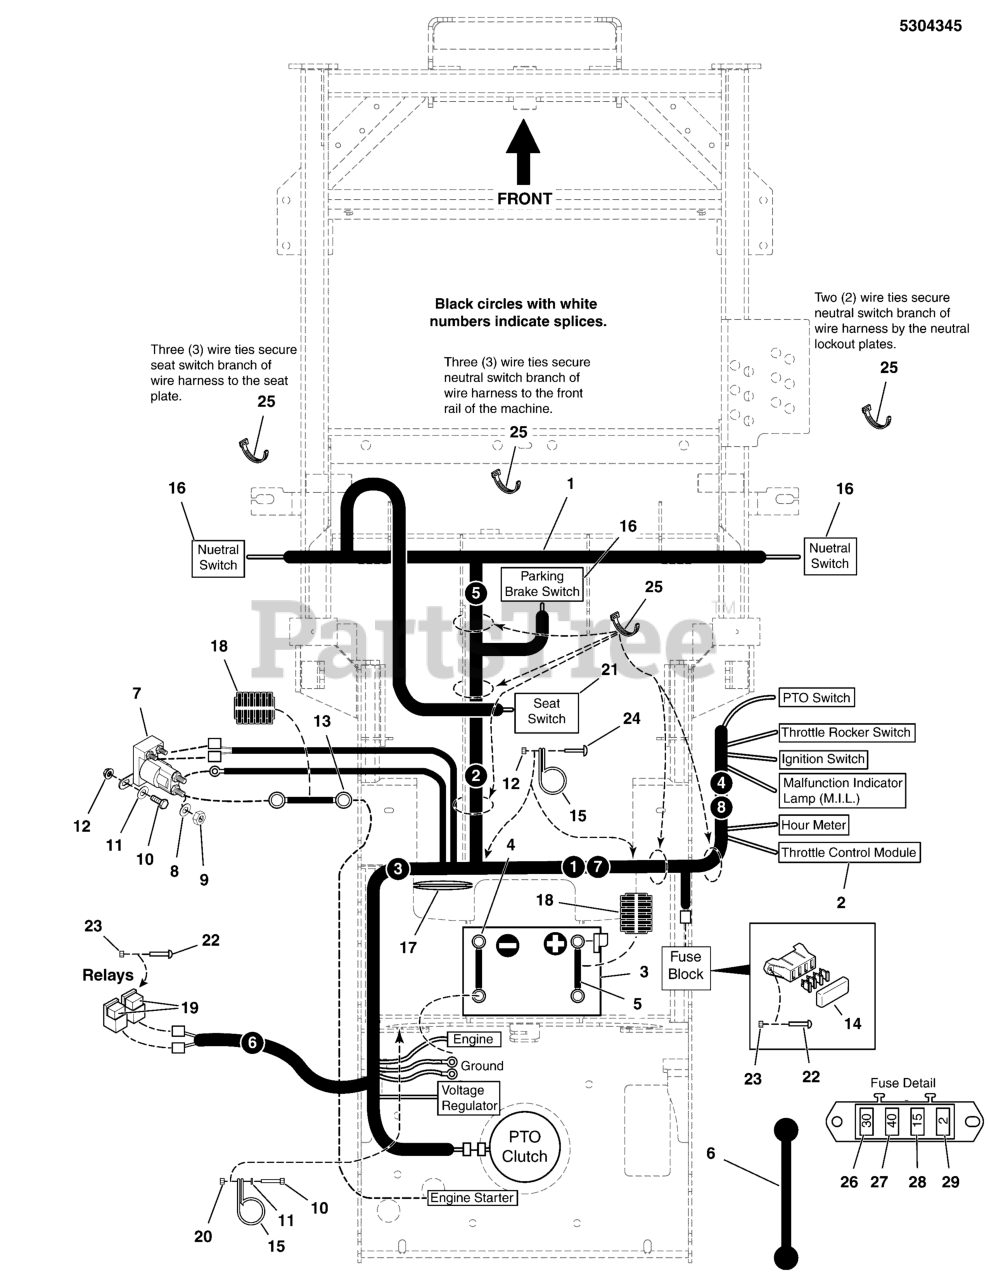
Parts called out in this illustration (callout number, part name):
1	WIRE HARNESS, IS700, KAWI FS730V EFI
2	MODULE, THROTTLE CONTROL, KAV DFI
3	BATTERY, WET ( BCIU1, 350 CCA)
4	BATTERY CABLE, NEG, 14, 5/16-13/32
5	BATTERY CABLE, POS, 22, 1/4-5/16
6	STRAP-BLACK RUBB
7	SOLENOID-4 POLE 12 VOLT DC (TROMBETTA)
8	WASHER, 5/16 LIGHT LOCK
9	NUT, 5/16-24 JAM
10	BOLT, 1/4-20 X 3/4 GD5 CZ
11	WASHER, 1/4 SAE
12	NUT, 1/4-20 HEX SERR. FLANGE
13	BATTERY CABLE, POS, 22, 1/4-5/16
14	COVER, VINYL, FUSE BLOCK
15	CLAMP, VINYL INSULATED, 1.00
16	SWITCH, DP NO/NC SNAP-IN
17	GROMMET, 1-1/2" ID FOR 1/4" METAL
18	WIRE LOOM, 3/8 ID X 18 IN
19	RELAY, 12V, 40A
20	NUT, 1/4-20 HEX NYLOCK FLANGE
21	DELTA SWITCH - NORMALLY CLOSED
22	SCREW, #10-24 X 3/4 ROUND PHILLIPS
23	NUT, #10-24 HEX NYLON LOCK
25	TIE, SELF-LOCKING, 12"
26	FUSE, ATO, 30 AMP
27	FUSE, ATO, 40A
28	FUSE, ATO-15 (15 AMP)
29	FUSE, 2 AMP, 32 VOLT, ATO-2
